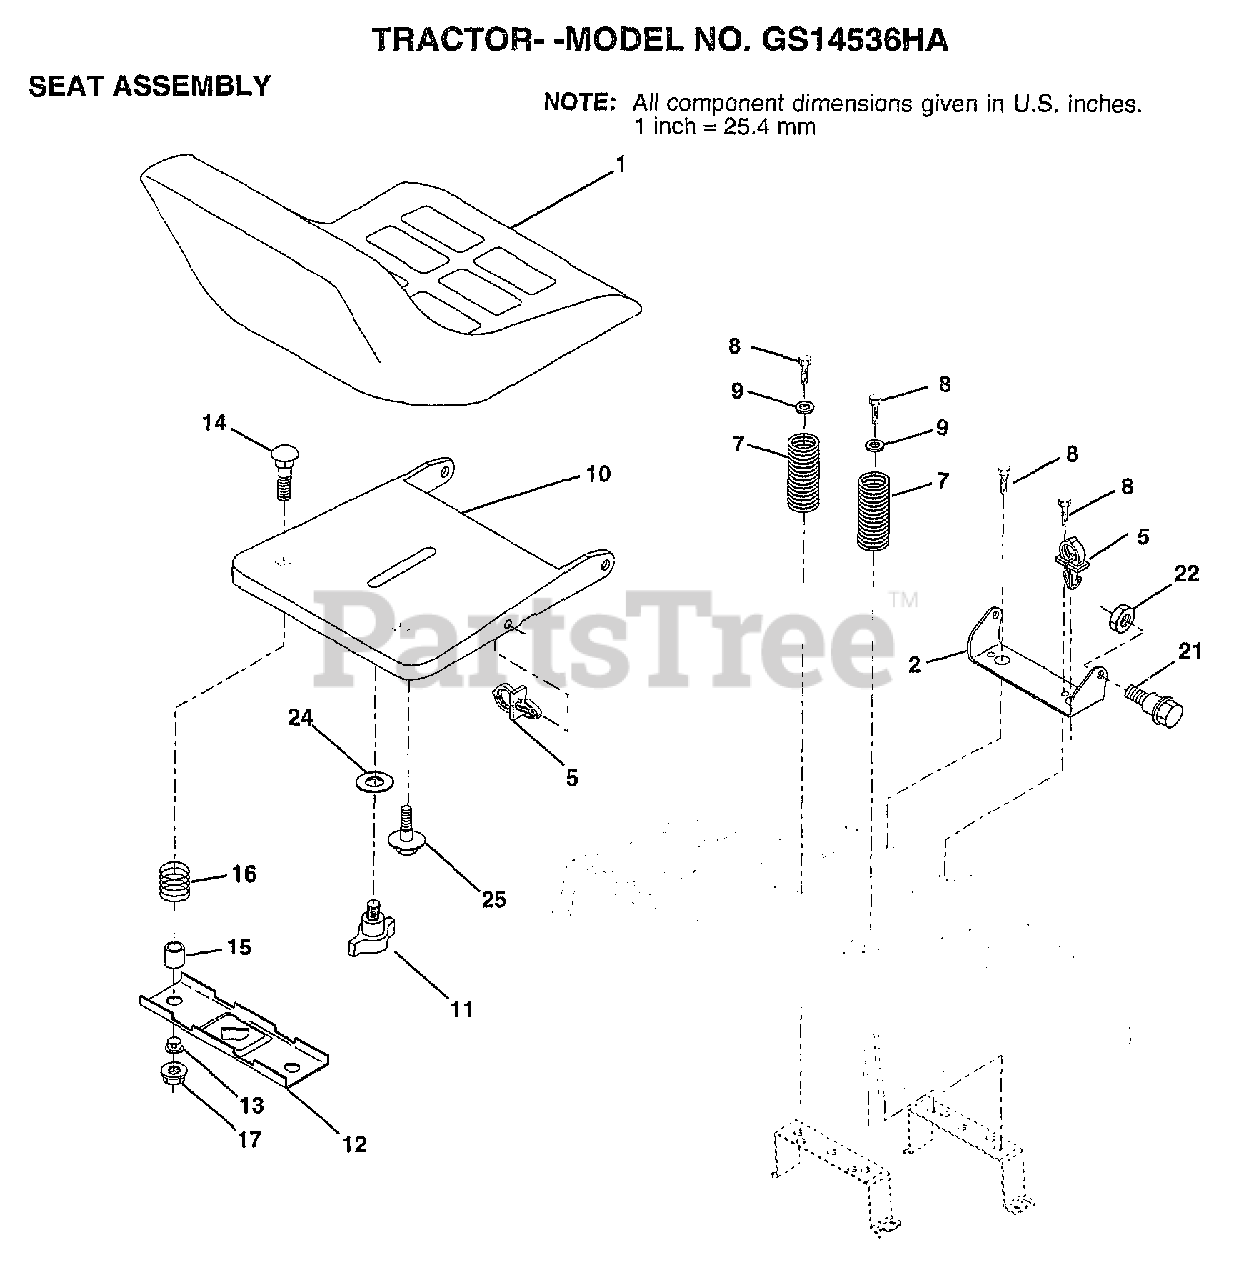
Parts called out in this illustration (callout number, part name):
1	SEAT.2500/1516.BK
2	BRACKET PVT SEAT
5	CLIP.PUSH-IN.HING
7	SPRING COMPRESSIO
8	SCREW GTV
9	WASHER
10	PAN-SEAT
11	KNOB.SEAT.ADJ.WINGNUT
12	BRKT SWITCH
13	BUSHING
14	BOLT-RD HD SQ NK
15	SPACER SPLIT
16	SPRING COMPRESSED
21	"BOLT,SHOULDER"
22	NUT
24	WASHER
25	"BOLT,SHOULDER"
